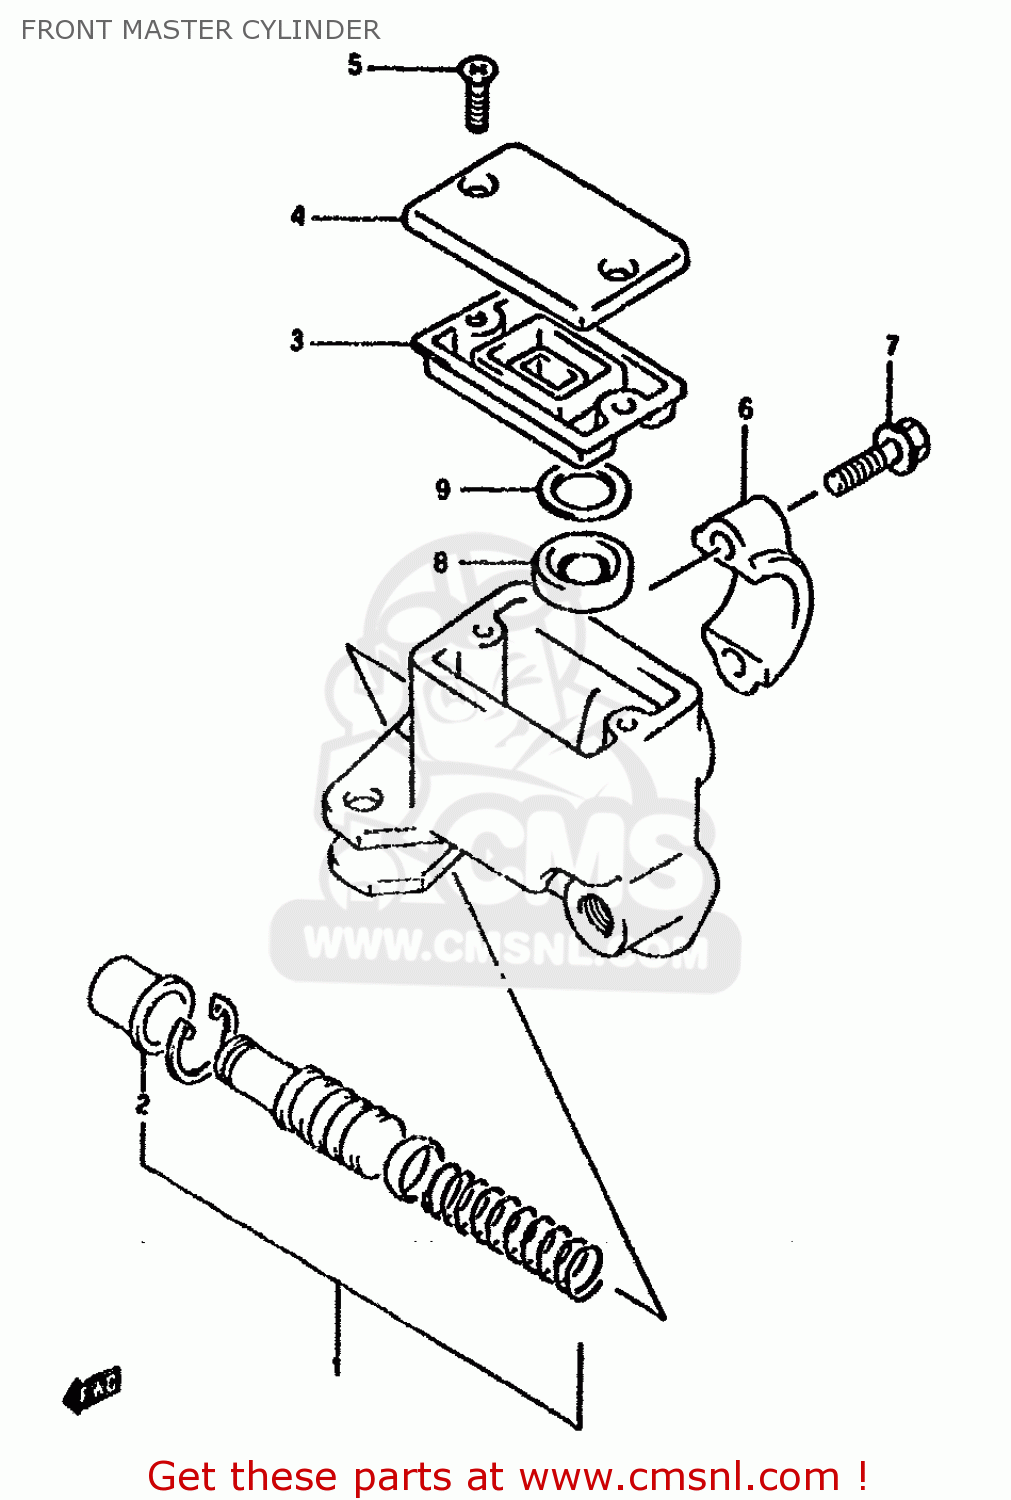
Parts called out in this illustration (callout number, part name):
1	PISTON & CUP SET
2	BOOT
3	DIAPHRAGM
4	CAP
5	SCREW
6	HOLDER
7	BOLT(6X25)
8	SEPERATOR
9	PLATE
